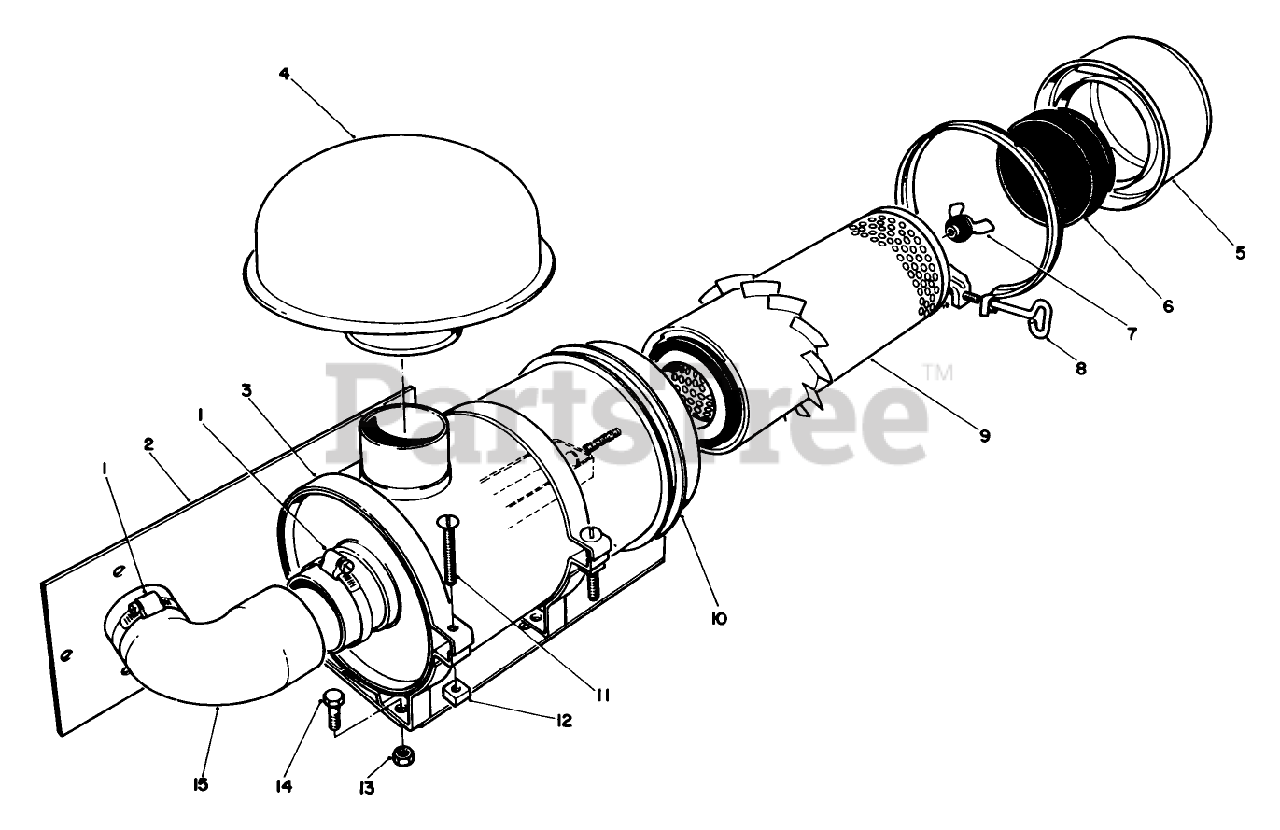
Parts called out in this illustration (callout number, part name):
1	CLAMP-HOSE
2	BRACKET-MOUNTING
3	MOUNTING BAND ASM
4	HOOD-INLET, AIR
10	Body Assembly
11	SCREW
12	NUT-SQUARE
13	NUT-LOCK, NI
14	SCREW-HH
15	HOSE-REMOTE, AIR CLEANER
